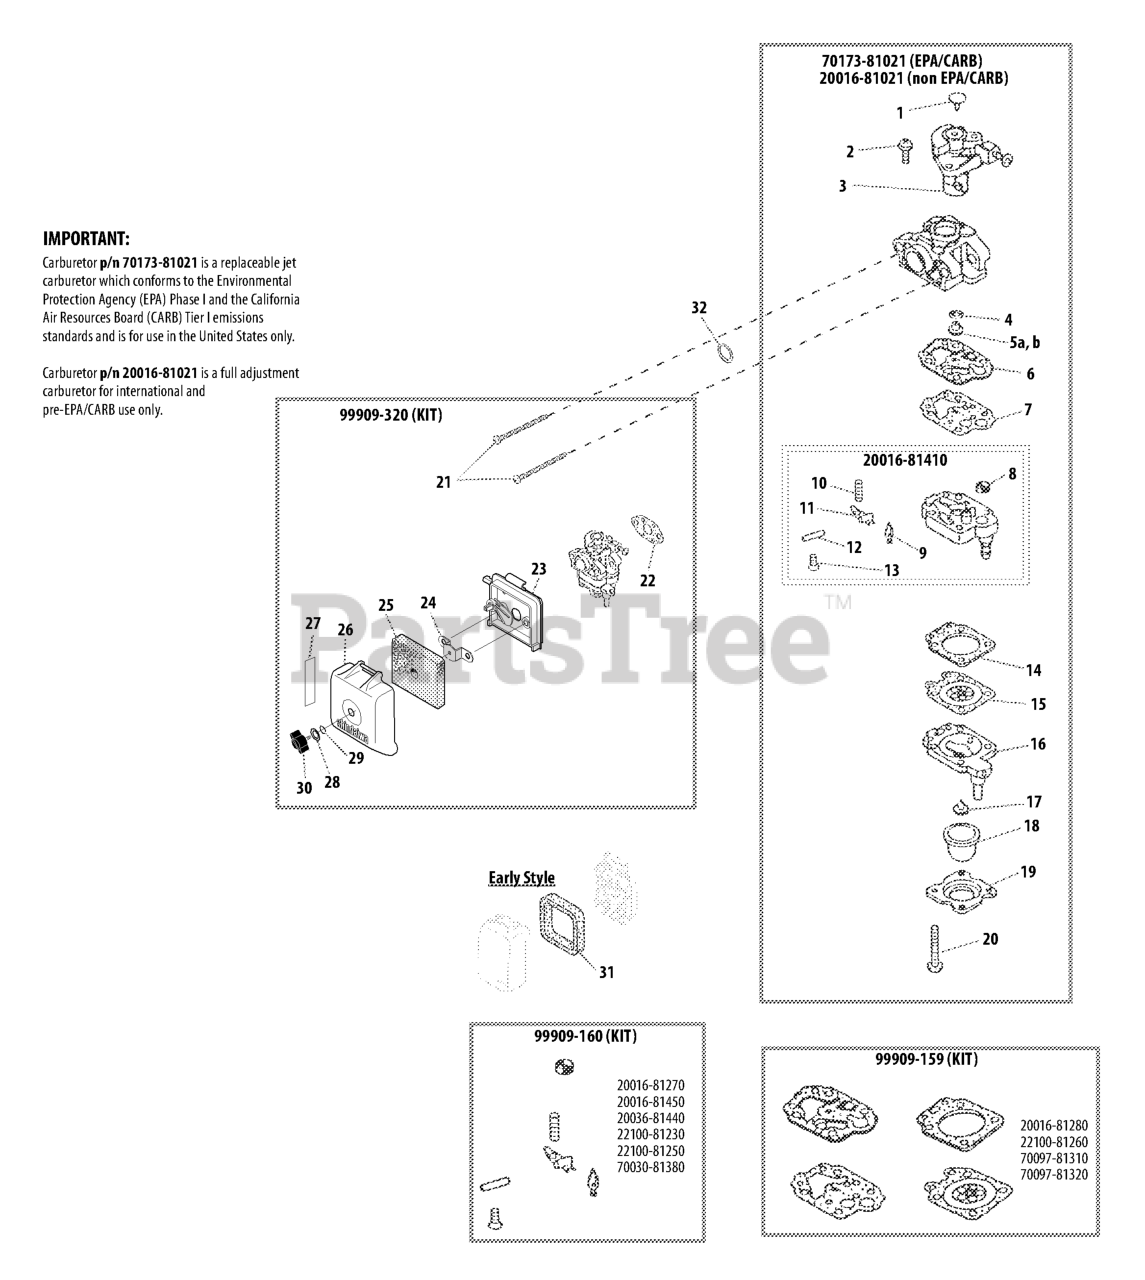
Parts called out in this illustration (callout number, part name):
1	PLUG, WELCH
2	SCREW
3	THROTTLE VALVE ASSY
4	O-RING
5	JET, MAIN - 38
5	JET, MAIN - 1000M #40
6	GASKET, PUMP
7	DIAPHRAGM, PUMP
8	STRAINER
9	VALVE, INLET NEEDLE
10	SPRING, METERING LEVER
11	LEVER, METERING
12	PIN, METERING LEVER
13	SCREW, METERING LEVER PIN
14	GASKET, METERING
15	DIAPHRAGM, METERING
16	BASE, PURGE
17	VALVE, CHECK
18	BULB, PURGE
19	RETAINER, PURGE BULB
20	SCREW, PUMP COVER
21	SCREW - 5X67
22	GASKET
23	CASE, AIR FILTER
24	PLATE, PREVENT
25	FILTER, AIR - FOAM
26	COVER, AIR FILTER
27	LABEL - CHOKE
28	WASHER - CONICAL
29	O-RING
30	THUMBSCREW
31	FILTER, AIR
32	O-RING - 15
20016-81021	CARBURETOR
20016-81410	PUMP BODY ASSY
70173-81021	CARBURETOR
99909-159	DIAPHRAGM/GASKET KIT
99909-160	REPAIR KIT
99909-320	AIR FILTER ASSY
